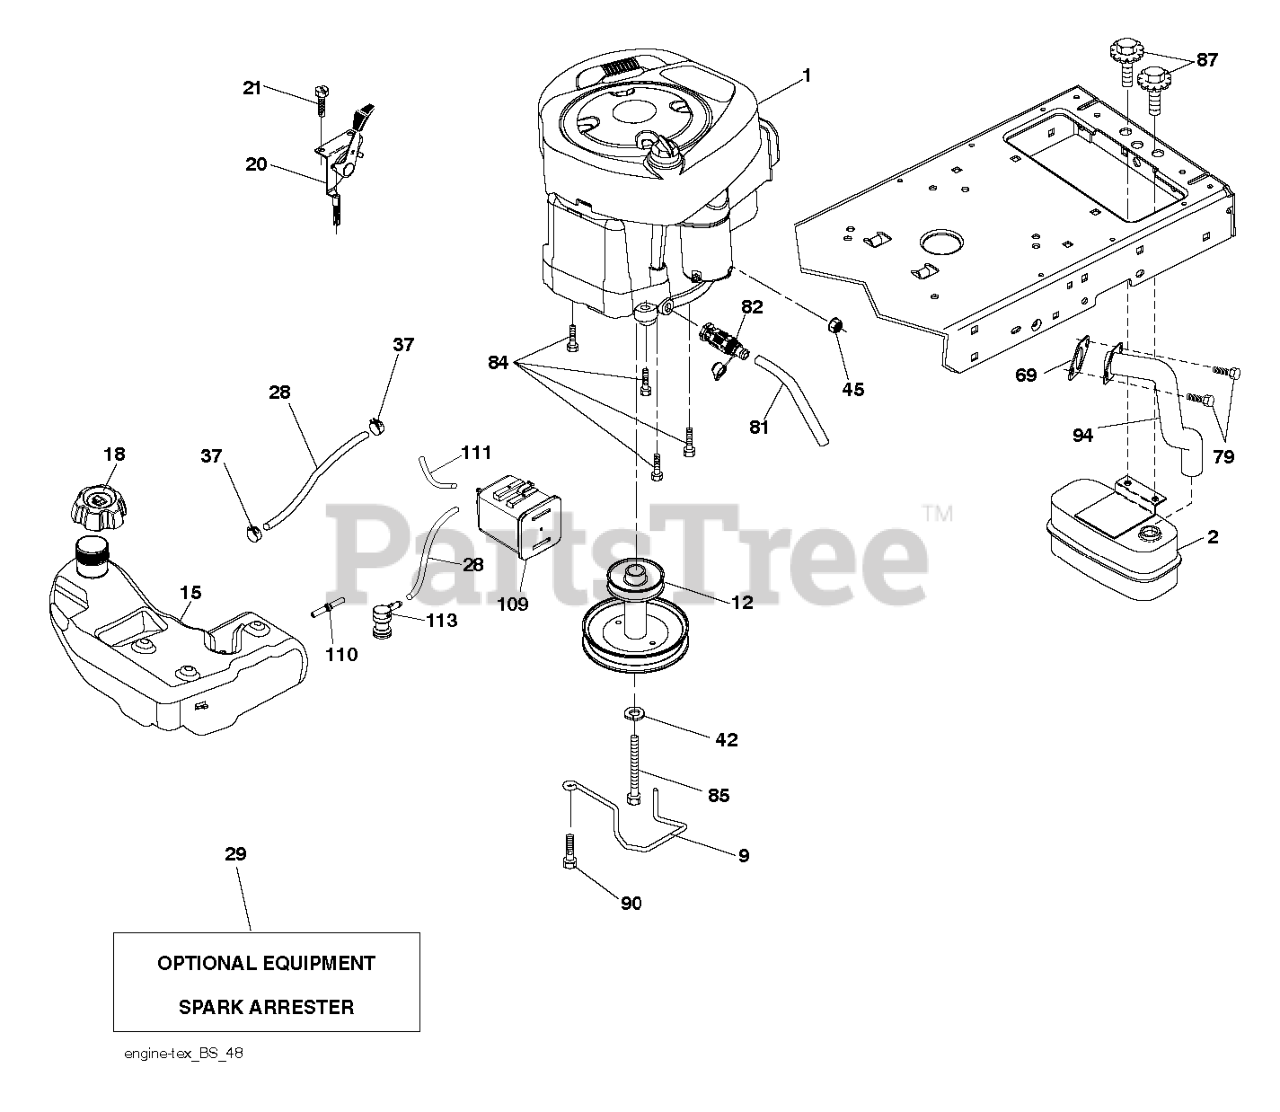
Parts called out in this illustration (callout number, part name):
2	MUFFLER.ASM.SNGL.XTNDED.DFLCTR
9	KEEPER.BELT.ENGINE.4.2
12	PULLY ENGINE
15	TANK.ASM.FUEL.3GA.CARB
18	CAP.ASM.FL.RITCH.3"E10.SYM.498
20	CONTROL.TH/CK.COBRA.KO
21	SCREW.#10 X 0.750.BOS
28	LINE.FUEL.64"REAR.EMIS
29	KIT.SPARK ARRESTOR 794945 B&S
37	HOSE CLAMP
42	LOCKWASHER
45	NUT
69	REPL BY 532 27 22-93
79	SCREW.SOCKET HD.5/16-1
81	TUBE, DRAIN OIL ASM.
82	VALUE.OIL.DRAIN
84	SCREW.3/8-16
85	BOLT HEX 7/16-20X4-1/4"
87	BOLT.5/16-18UNCX3/4 W/SEMS.BLK
90	SCREW 3/8-16X1
94	RP.EXHAUST.TUBE.B&S.28/31
109	CANNISTER, CARBON
110	VALVE.ASM.ANTI-SLOSH
111	RP PURGE LINE
113	VALVE.SLANT.CARTRDG.90 DEG.TEX
